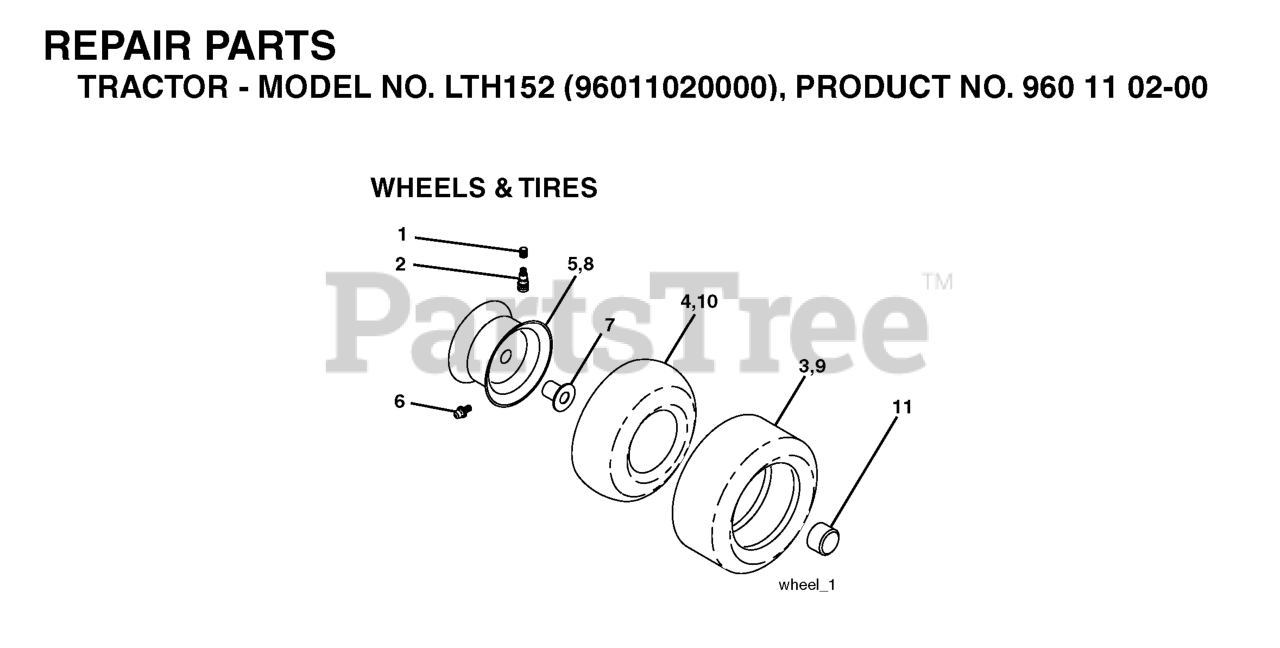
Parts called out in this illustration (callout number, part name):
2	VALVE STEM LT
3	TIRE HEAVY DUTY
4	TUBE.5.3/4.5/6
5	RIM ASM 6" FRONT SILVER
6	FITTING LT
7	BEARING T
8	RIM ASM 8" REAR SILVER
9	TIRE HEAVY DUTY
10	TUBE
11	CAP, AXLE BLK
